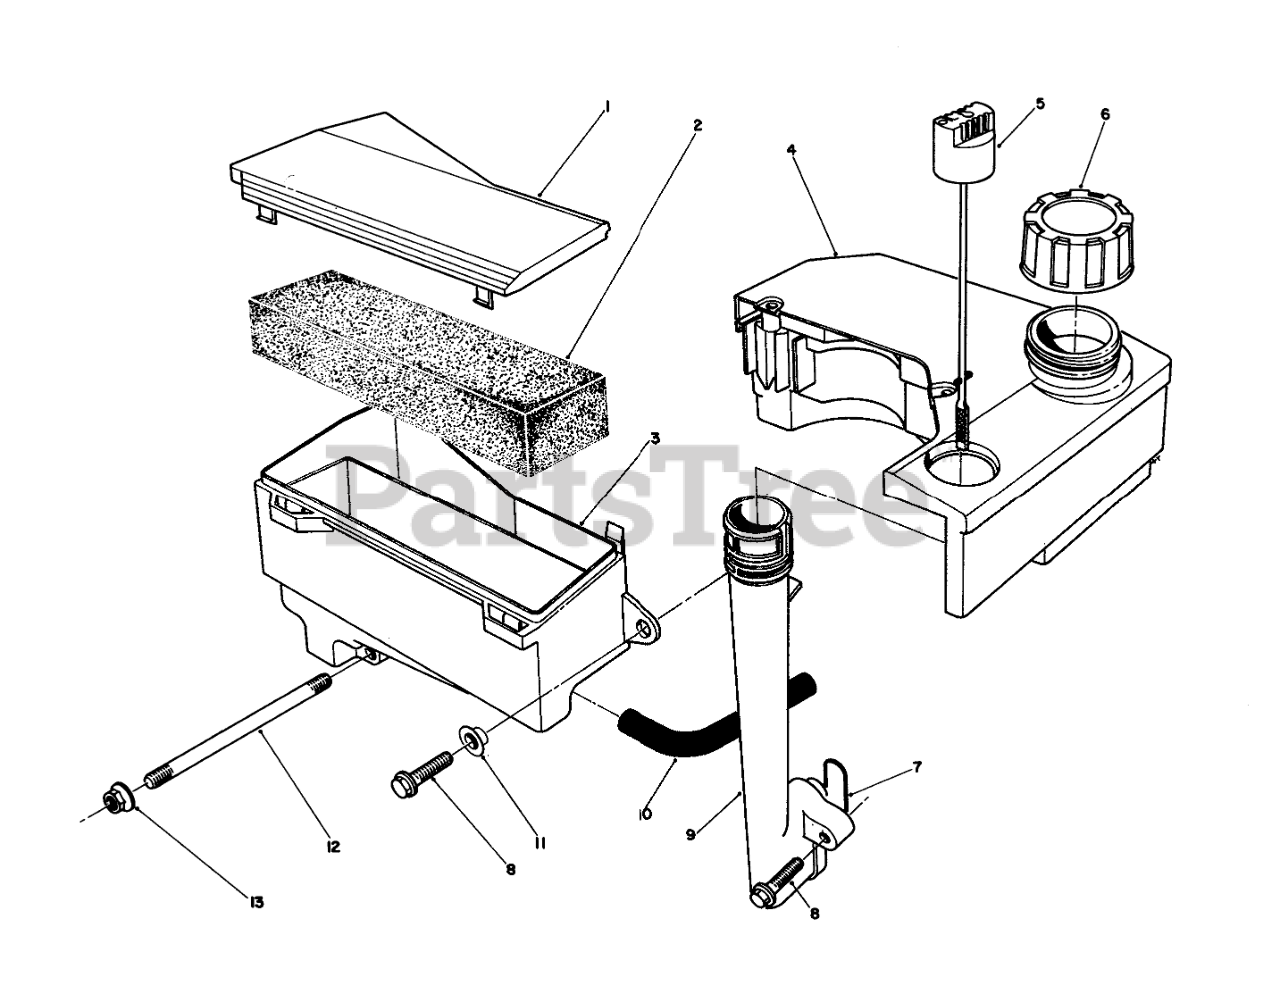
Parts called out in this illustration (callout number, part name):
1	AIR CLEANER CAP
3	Body-Air Cleaner
4	TANK ASM
5	Dipstick
6	GAS CAP ASM
7	O-RING
11	SPACER
12	Stud-Carburetor
